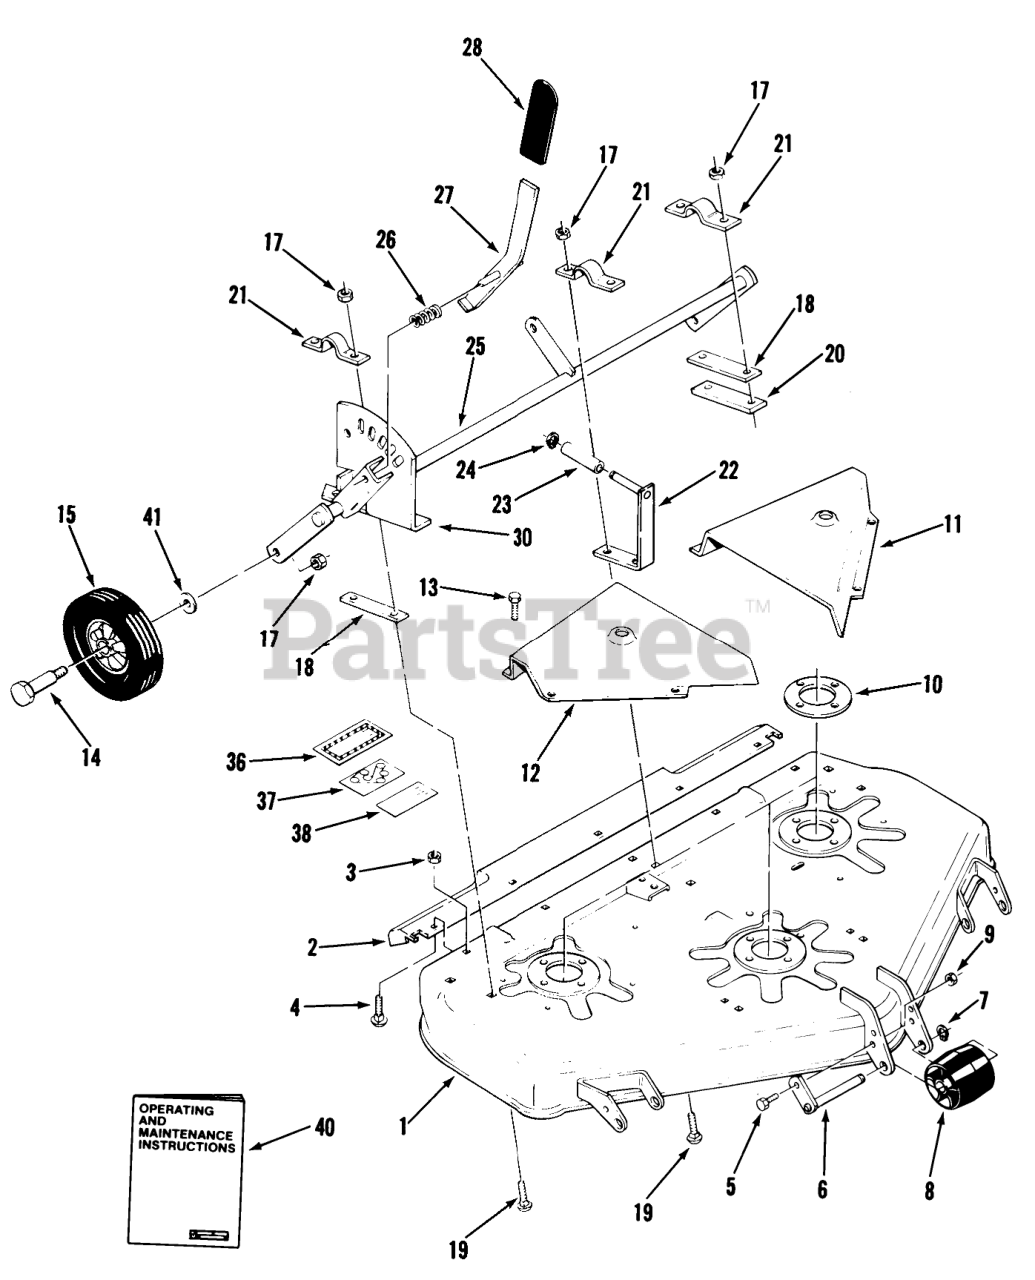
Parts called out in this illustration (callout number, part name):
1	Mower Deck
2	EXTENSION R
3	Nut
4	CARRIAGE BOLT -4
5	H H C S
6	Roller Shaft
7	Retaining Ring
8	Roller
9	Nut
10	PLATE-SPINDLE
11	Belt Cover LH
12	Belt Cover RH
13	Bolt
14	BOLT-SHOULDER
15	Wheel 6 x 1.75
17	Nut
18	Strap 1/16
19	Bolt
20	Strap
21	CLAMP
22	Bracket Guide
23	SPACER
24	Snap Ring
25	Gage Wheel Support
26	SPRING-COMPRESSION
27	Lever
29	HANDLE-EXTENSION R
30	Quadrant
31	Bolt
32	Nut
33	Bolt
34	Wheel Plate
35	Nut
36	Caution Decal
37	DECAL-HEIGHT BELT
38	Decal-Caution
39	STEERING ARM
40	Operating and Maintenance Instructions
41	WASHER
